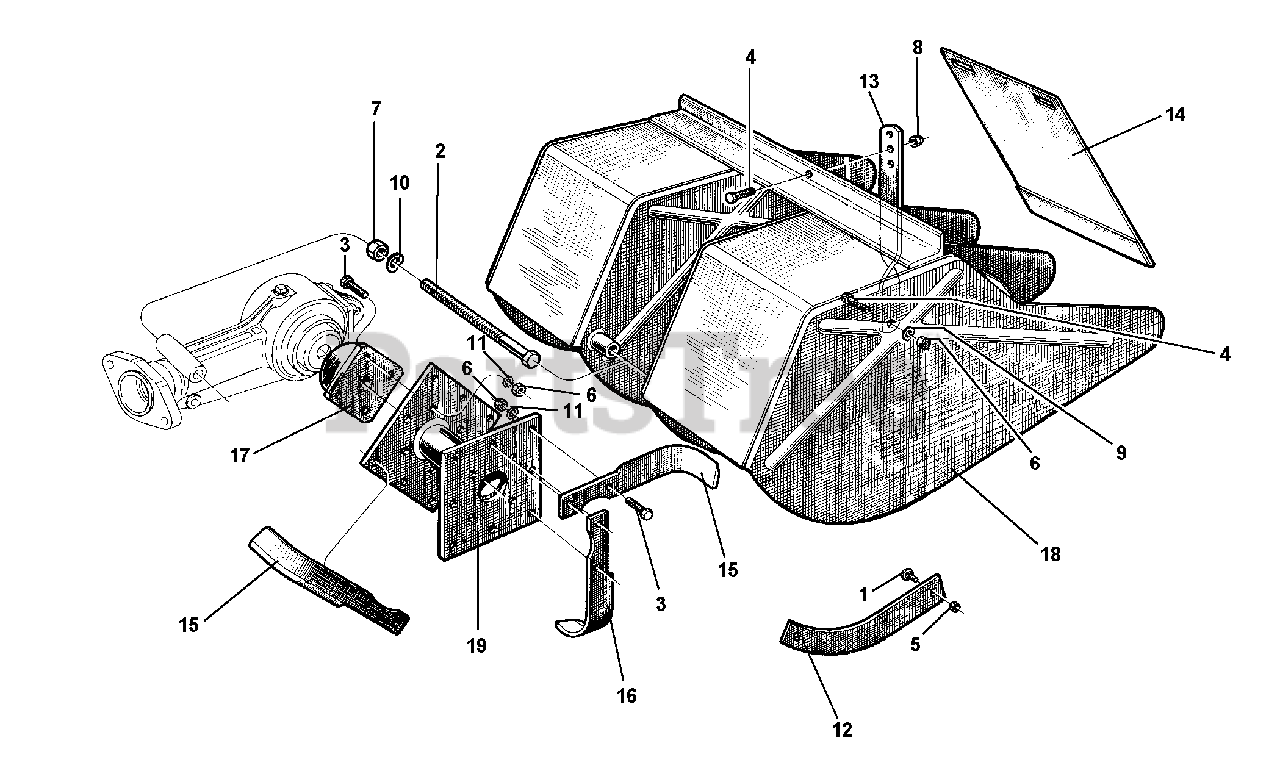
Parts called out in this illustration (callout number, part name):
1	BOLT M6 X 12 & SQUARE NUT
2	SCREW TE M12 X 150 UNI 5739-S
3	SCREW M8 X 20
4	SCREW M8 X 25
8	NUT, SELF LOCKING M8
9	WASHER, LOCK 8.4
10	WASHER, LOCK 13
11	WASHER, LOCK AW 8.4
12	GUARD, INTERNAL
13	ROD, HOOD ADJUSTMENT
14	FLAP DOUBLE HOE HOOD
16	KNIFE, R.H.
17	FLANGE, BLADE HOLDER
18	HOOD, DOUBLE CUTTER
